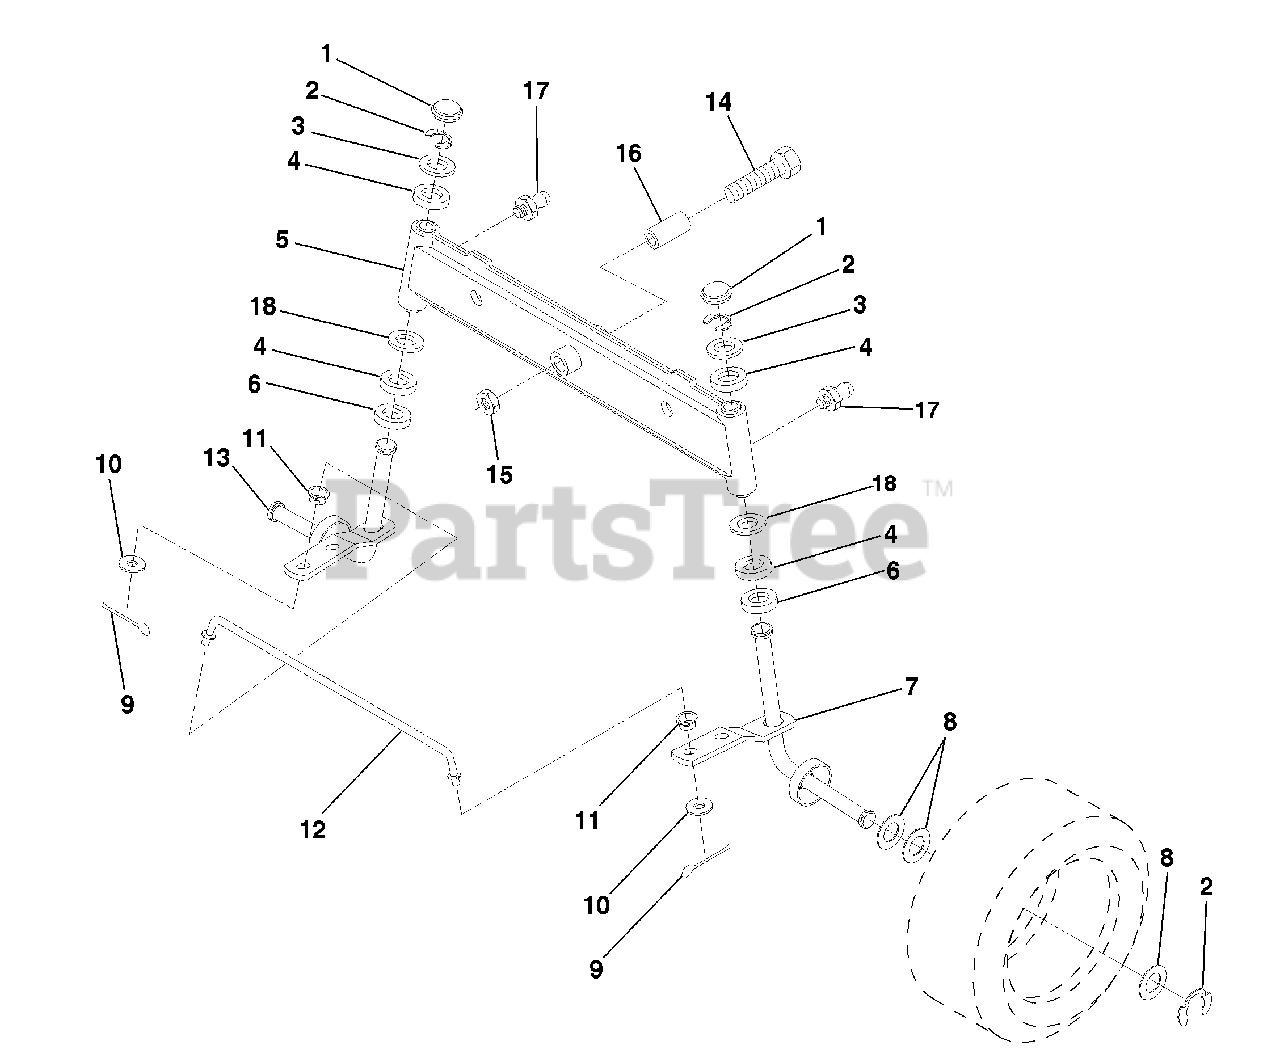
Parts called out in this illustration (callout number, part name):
1	Cap, Spindle
2	Ring, Clip
3	Washer 25/32 x 1-5/8 x 16 Ga.
4	Nyliner
5	Axle, Front
6	Bearing, Thrust
7	Spindle, R.H. Asm.
8	Washer 25/32 x 1-1/4 x 16 Ga.
9	Pin, Cotter 1/8 x 3/4
10	Washer 13/32 x 13/16 x 16 Ga.
12	Rod, Tie
13	Spindle, L.H. Asm.
14	Bolt Hex 5/1-11 x 3-1/2
15	Nut, Lock Flange 5/8-11
16	Spacer, Bearing Axle
17	Fitting, Grease
18	Washer 27/32 x 1-1/4 x 16 Ga.
